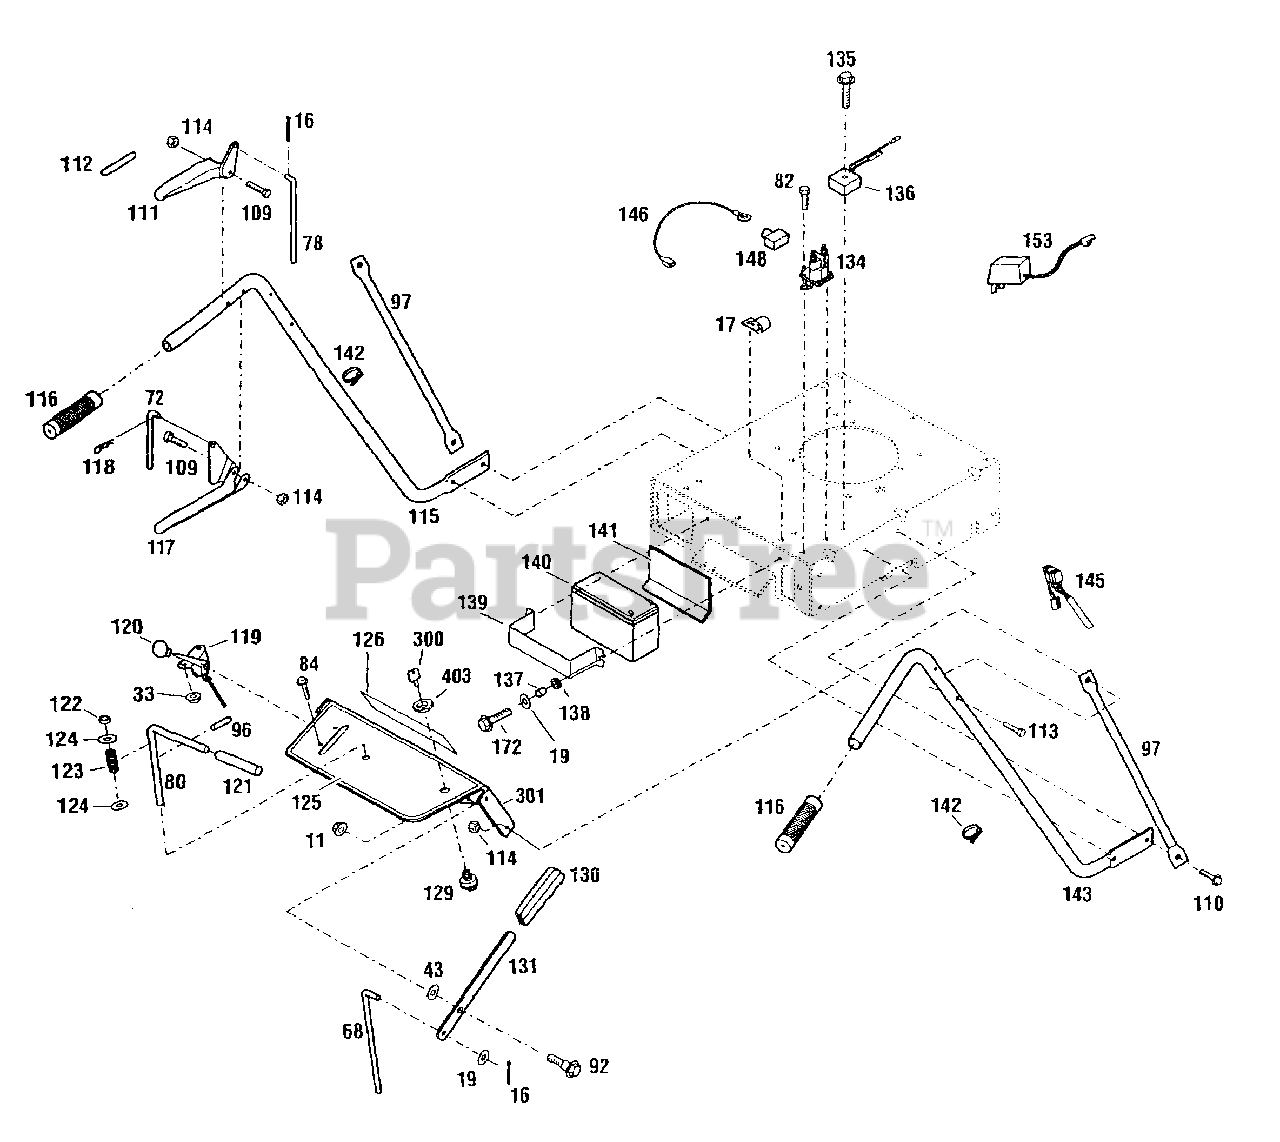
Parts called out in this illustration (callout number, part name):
11	Flange Locknut, 3/8-16
16	Cotter Pin, 3/32 x 5/8
17	J-Clip
19	Flat Washer, 5/16
33	Flange Locknut, 1/4-20
43	Flat Washer, 1/2
68	Upper Blade Rod
72	Upper Transmission Rod
78	Upper Brake Rod
80	Shift Rod
82	Thread Cut. Screw, 1/4-20 x 1/2
84	Flange Lock Screw, 1/4-20x 1/2
92	Shoulder Bolt
96	Roll Pin, 1/4 x 2-1/4
97	Brace, Handlebar
109	Hex Screw, 1/4-20 x 1-3/4
110	Flange Lock Screw, 5/16 x 3/4
111	Control Handle
112	Operator Presence Control Decal
113	Hex Screw, 1/4-20 x 1-3/4, Grade 8
114	Locknut,1/4-20
115	Left Handlebar
116	Handle Grip
117	Control Handle
118	Hair Pin, 5/64
119	Throttle Control
121	Handle Grip
122	Nylon Bushing
123	Compression Spring
124	Flat Washer, 1 /2
125	Warning Decal
126	Logo Decal
129	Ignition Switch
130	Handle Grip
131	Mower Engage Lever
134	Solenoid
135	Thread-Cut. Screw, 1/4-20 x 1-1/2
136	Regulator
137	Spacer
138	Grommet
139	Battery Bracket
140	Battery
141	Battery Pad
142	Plastic Tie
143	Right Handlebar
145	Wiring Harness
146	Wire Lead
148	Boot
153	Battery Charger
172	Screw, 5/16-18 x 3/4"
300	Ignition Key
301	Console Assembly
